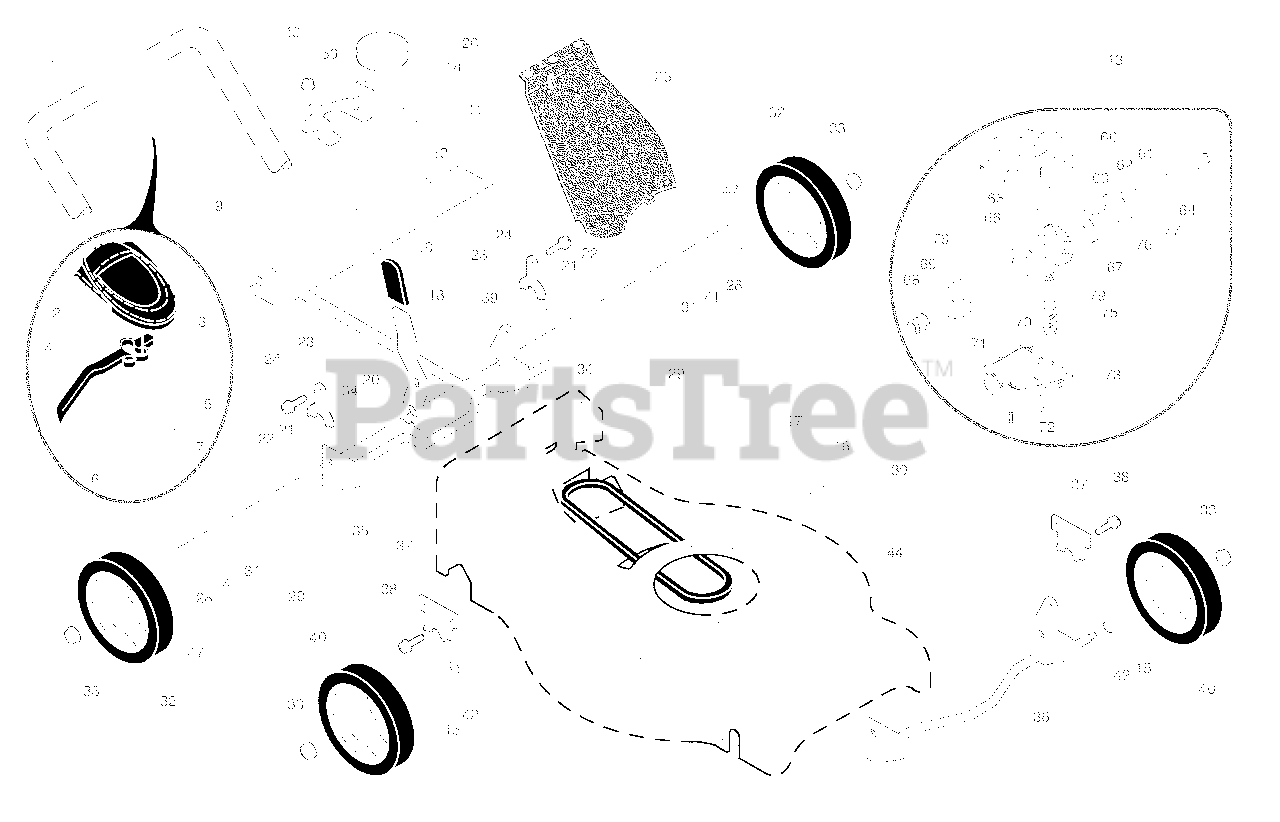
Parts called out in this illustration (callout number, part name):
1	Drive Control Assembly, Auto-Walk
2	Cover, Top, Auto-Walk Drive Control
4	Lever, Auto-Walk Drive Control
5	Cover, Bottom, Auto-Walk Drive Control
6	Screw, Phillips Head #10 x 5/8
7	Plate, Trigger, Auto-Walk Drive Control
9	Cable, Drive Control
11	Spring, Return
13	Gear Case Assembly
14	Pulley, Drive
15	Washer, Flat
16	Rod, Connecting
17	Spring, Extension
18	Spring Selector
19	Knob, Selector Spring
21	Bearing, Support
22	Bearing, Ball
23	Retainer, Drive Assembly, Stamped
24	Screw, Tapping, Hex Head 1/4-20 x 3/4
25	Cover Drive
26	Screw, Threaded, Rolled #10-25 x 1/2
28	E-Ring 7/16
29	Cover, Dust, Wheel
31	Pawl, Drive
32	Wheel & Tire Assembly, Rear
33	Nut, Hex, Flangelock 3/8-16
35	Shaft Assembly, Rear
36	Shaft Assembly, Front
37	Retainer, Front Shaft
38	Screw, Hi-Lo Thread #12 x 5/8
39	Bolt, Shoulder, Semi-Gimlet Point
40	Wheel & Tire Assembly, Front 8 x 1-3/4
47	Washer 1/2 x 1-1/2 x .134
49	Screw, Hi-Lo Thread #12 x 5/8
50	Belt Keeper
60	Case, Upper
61	Shaft, Output, Long
62	Seal, Output Shaft
65	Seal, Worm Shaft
66	Bearing, Ball
67	Gear, 28 Teeth
68	Fixed Dog Clutch, LH
69	Pin, Output Shaft
70	Movable Dog Clutch, LH
71	Shaft, Output, Short
72	Screw, Case
73	Case, Lower
75	Pin, Worm Shaft
76	Movable Dog Clutch, RH
77	Fixed Dog Clutch, RH
78	Spring, Leaf
79	Shaft, Worm
